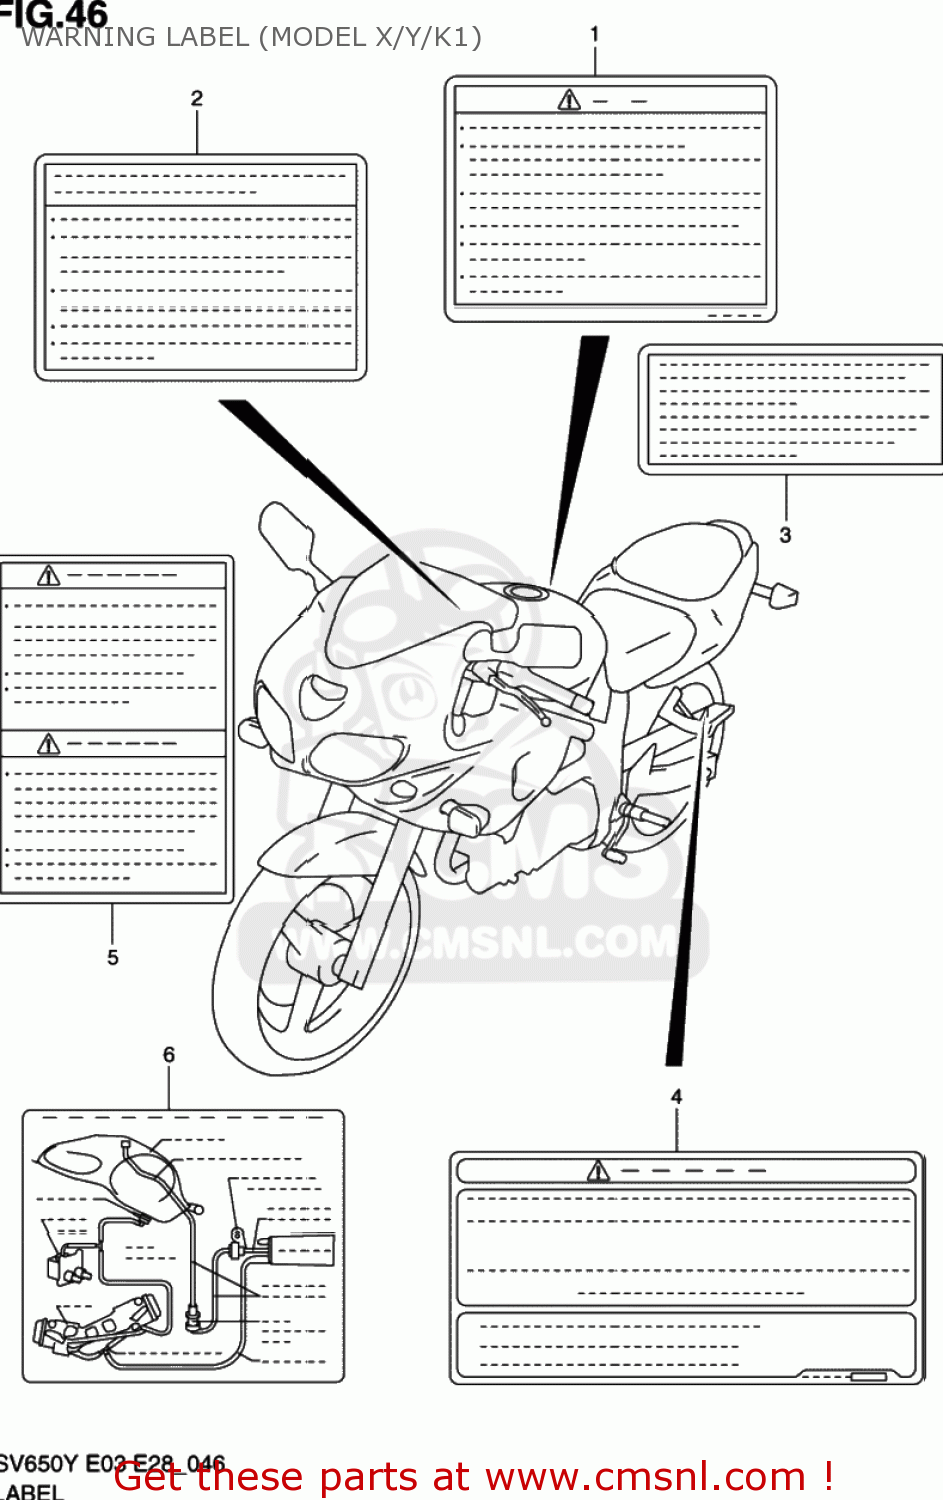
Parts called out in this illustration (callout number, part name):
1	LABEL,GENERAL WARNING
2	LABEL,WARNING SCREEN
3	LABEL (MANUAL NOTICE)
4	STICKER
5	LABEL,WARNING STEERING
6	LABEL,VACUUM HOSE ROUTING
7	MANUAL,OWNER'S
